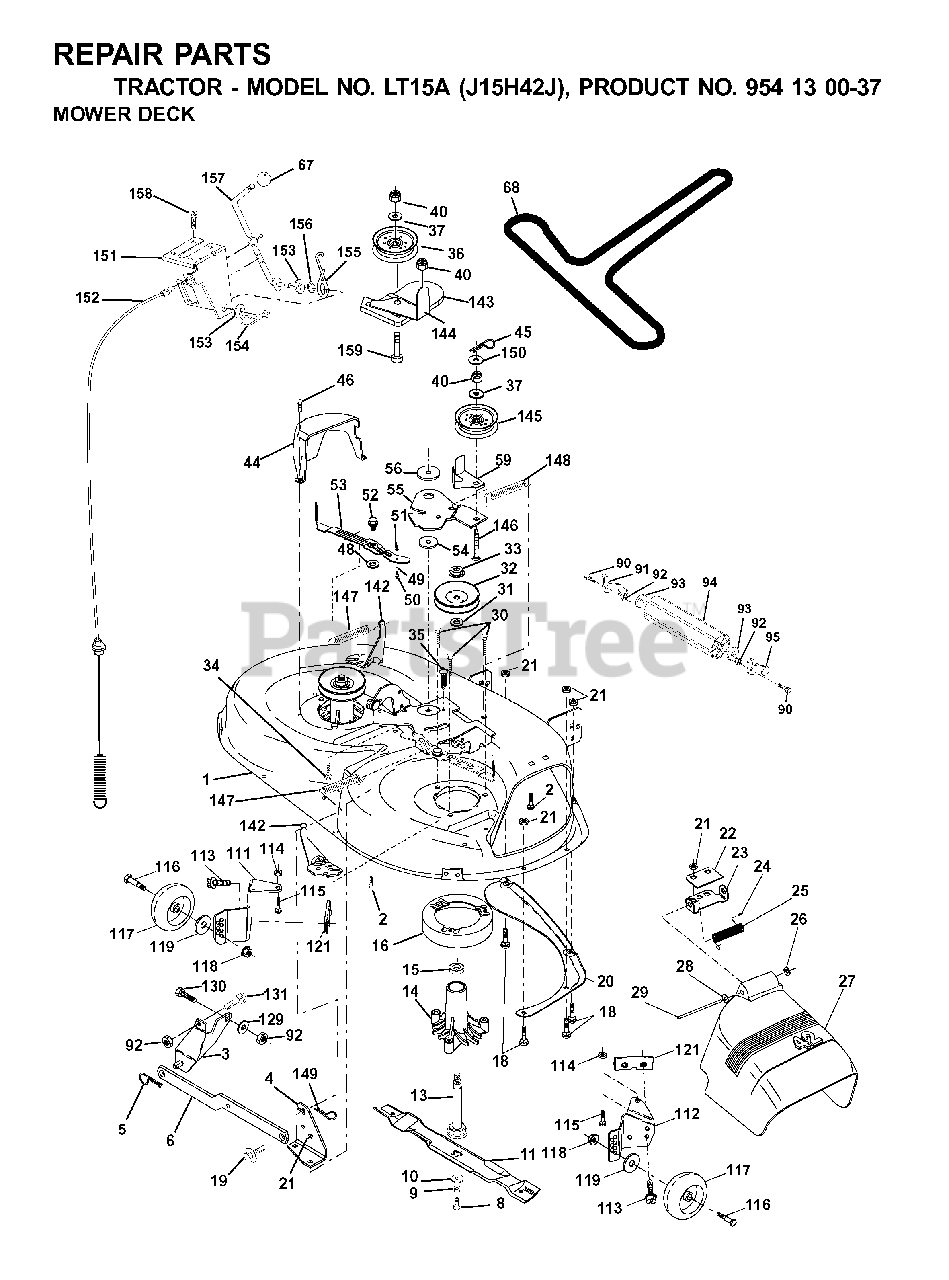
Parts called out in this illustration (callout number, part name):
1	42" DECK KIT
2	BOLT
3	BRKT ASM SWAY BAR
4	BRACKET SWAY BAR 42" DECK
5	RETAINER-SPRNG RB
6	REAR SUSP ARM
8	BLADE BOLT
9	LOCKWASHER
10	WASHER.BLADE
11	BLADE 42"
13	SHAFT ASM VENT
14	HSG MANDREL
16	STRIPPER
18	BOLT
19	BOLT SHD 5/16-18
20	BAFFLE.VORTEX
21	LOCKNUT
22	STIFFENER BRACKET
23	DEFLECTOR BRACKET
24	CAP-SLEEVE LT
25	SPRING TORSION
26	NUT PUSH M
27	SHIELD DEFLECTOR
28	WASHER
29	ROD.HINGE
30	SCREW THDROL ROLLING WASHER HD
31	WASHER
32	PULLEY/MANDREL
33	NUT
34	BOLT
35	FASTENER.XMAS.TREE
36	FLAT IDLER PULLEY
40	LOCKNUT
44	GUARD MANDREL LH BLACK
45	RETAINER M
46	SCREW.1/4-20X5/8
49	ROLLER ASM CAM FOLLOWER
50	BOLT
53	ARM
54	HARDENED WASHER
55	ARM IDLER 42" MOWER LT/YT
56	SPACER.RETAINER.MOWER
59	GUARD, BELT
67	KNOB T (3/8 HOLE)
68	BELT V SECONDARY
90	BOLT
91	BRACKET LH (A)
92	NUT
94	NOSE ROLLER
95	BRACKET RH (B)
111	BRACKET WHEEL GAUGE LH 42" DK
112	BRACKET WHEEL GAUGE RH 42" DK
114	NUT
115	BOLT
117	WHEEL.GAUGE.STANDARD
118	LOCKNUT
119	WASHER
121	BRACKET.EXTRD.GWL
129	WASHER
130	BOLT
131	BOLT D
142	ARM SPRING BRAKE MOWER
143	BRACKET, ARM IDLER
144	KEEPER.BELT.42".CLUTCH.CABLE
145	PULLEY
146	BOLT, CARRIAGE IDLER BLACK
147	SPRING EXTENSION
148	IDLER RETURN SPRING
149	SPRING.RETAINER.YELLOW.ZINC
150	WASHER PM
151	BRACKET, CLUTCH CABLE
152	CLUTCH CABLE 42"
153	WASHER FLAT 3/8"
154	SPRING RETAINER
155	SPRING RETENTION LEVER
156	SPACER CLUTCH CABLE
157	ROD CLUTCH CABLE 3/8"
158	SCREW LT
159	BOLT
